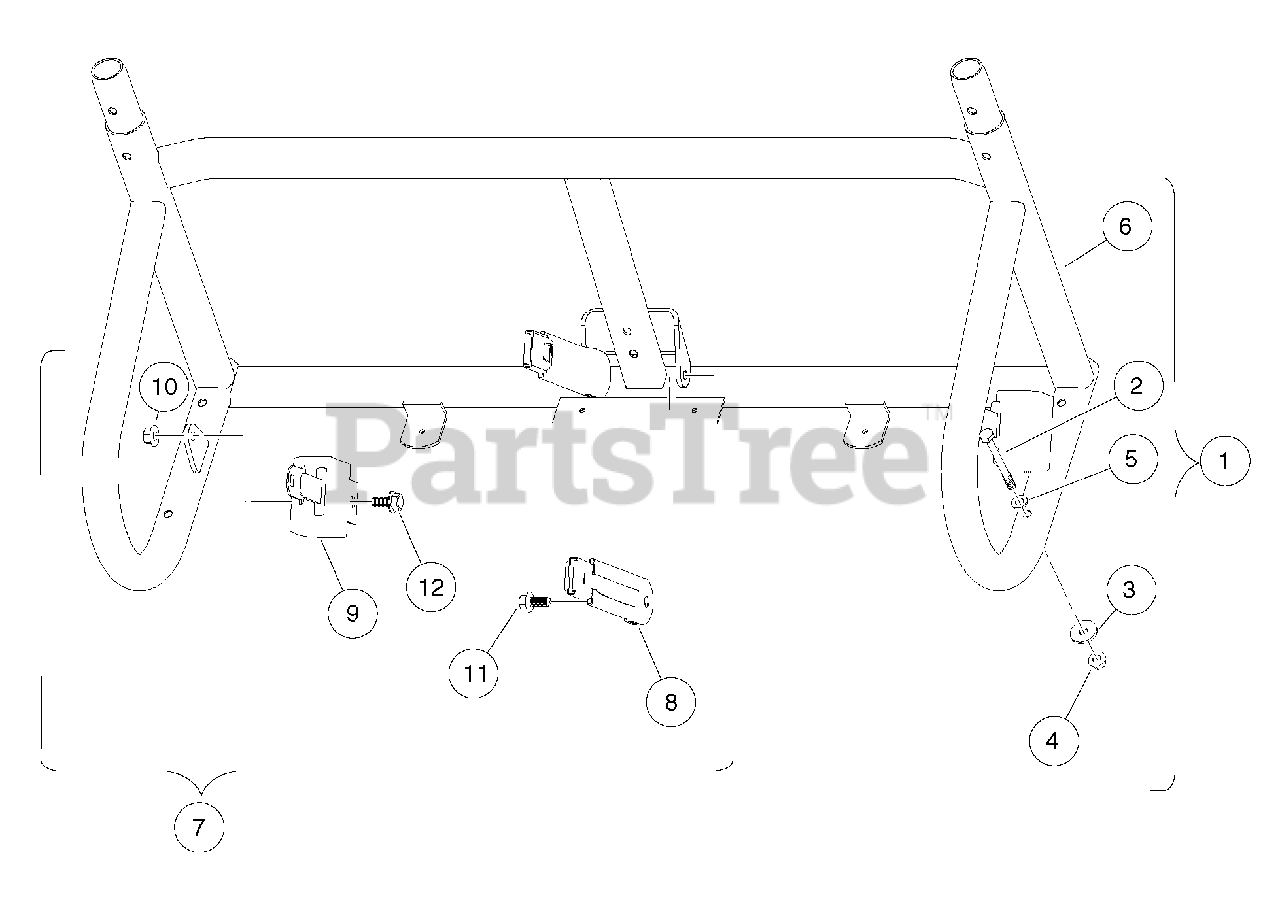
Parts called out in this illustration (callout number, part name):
1	Instl, Rops, Lower
2	Bolt, M10x1.50x100 (Black)
3	Washer Hard,m10
4	Nut Flg M10 X 1.5 Mech Def
5	Washer, Hard, M10, Zn-Ni/Blk
6	Weldment,seat Support,hs,rops
7	Instl, Seat Belt, Restyle
8	Buckle, Seat Belt with Sleeve
9	Retractor, Seat Belt
10	Ln Flg, M12 X 1.75, Md, Black
11	Screw,m12x1.75x30 Thd Form Blk
12	Bolt Flg, M12x1.75 X 25 Black
